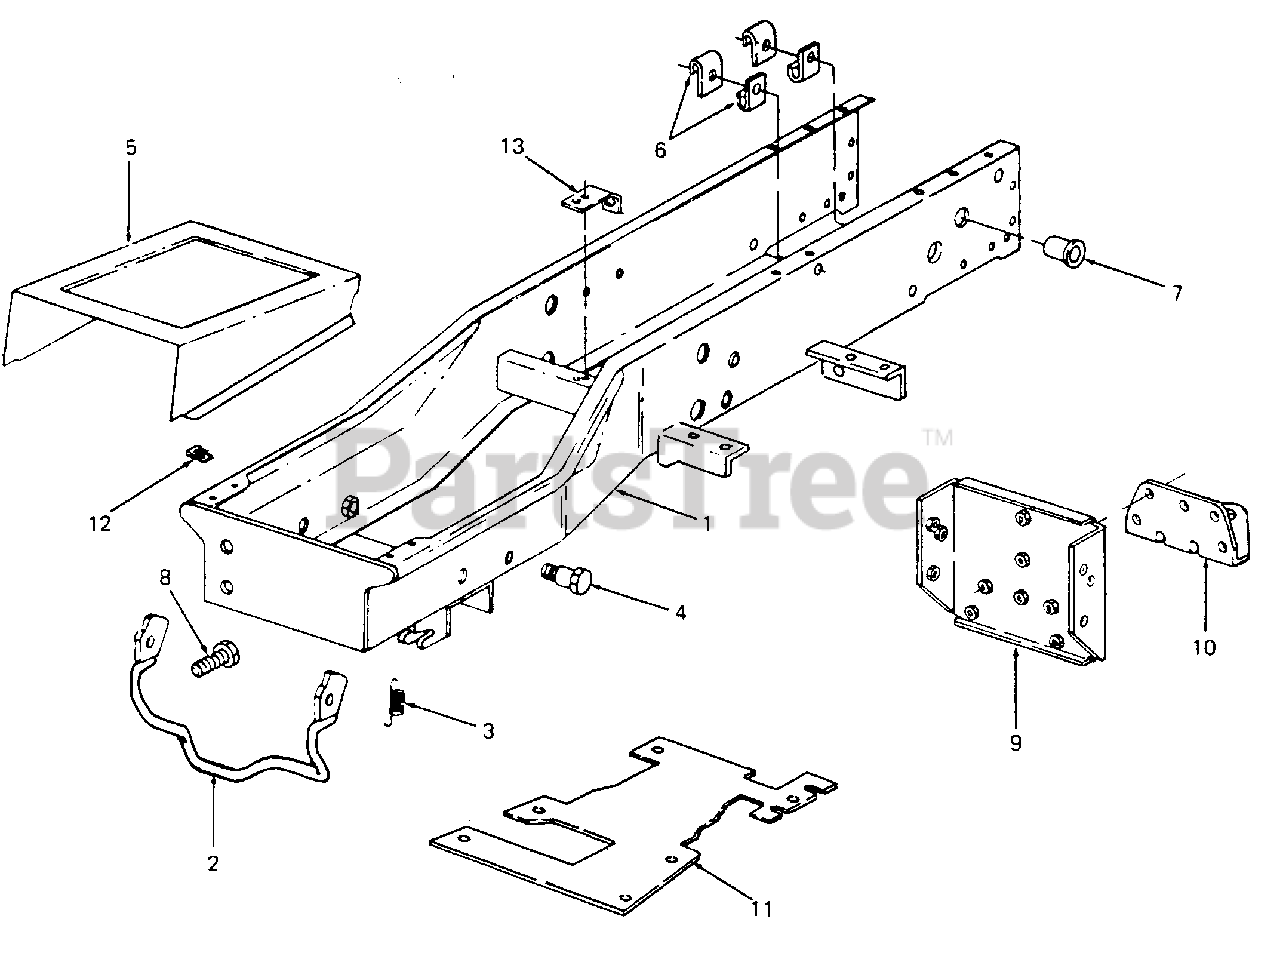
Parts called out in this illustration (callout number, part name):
3	Spring, Latch
4	Bolt, Shoulder
5	Cover, Frame w/Graphic
6	Clip, Cable
7	Bushing, Snap
8	Screw, Adjustment, 1/2-20 X 1.0 Lg GR5
9	Plate Assy, Hitch
11	Baffle, Lower Frame
12	Nut, Speed
13	Bracket, Switch
